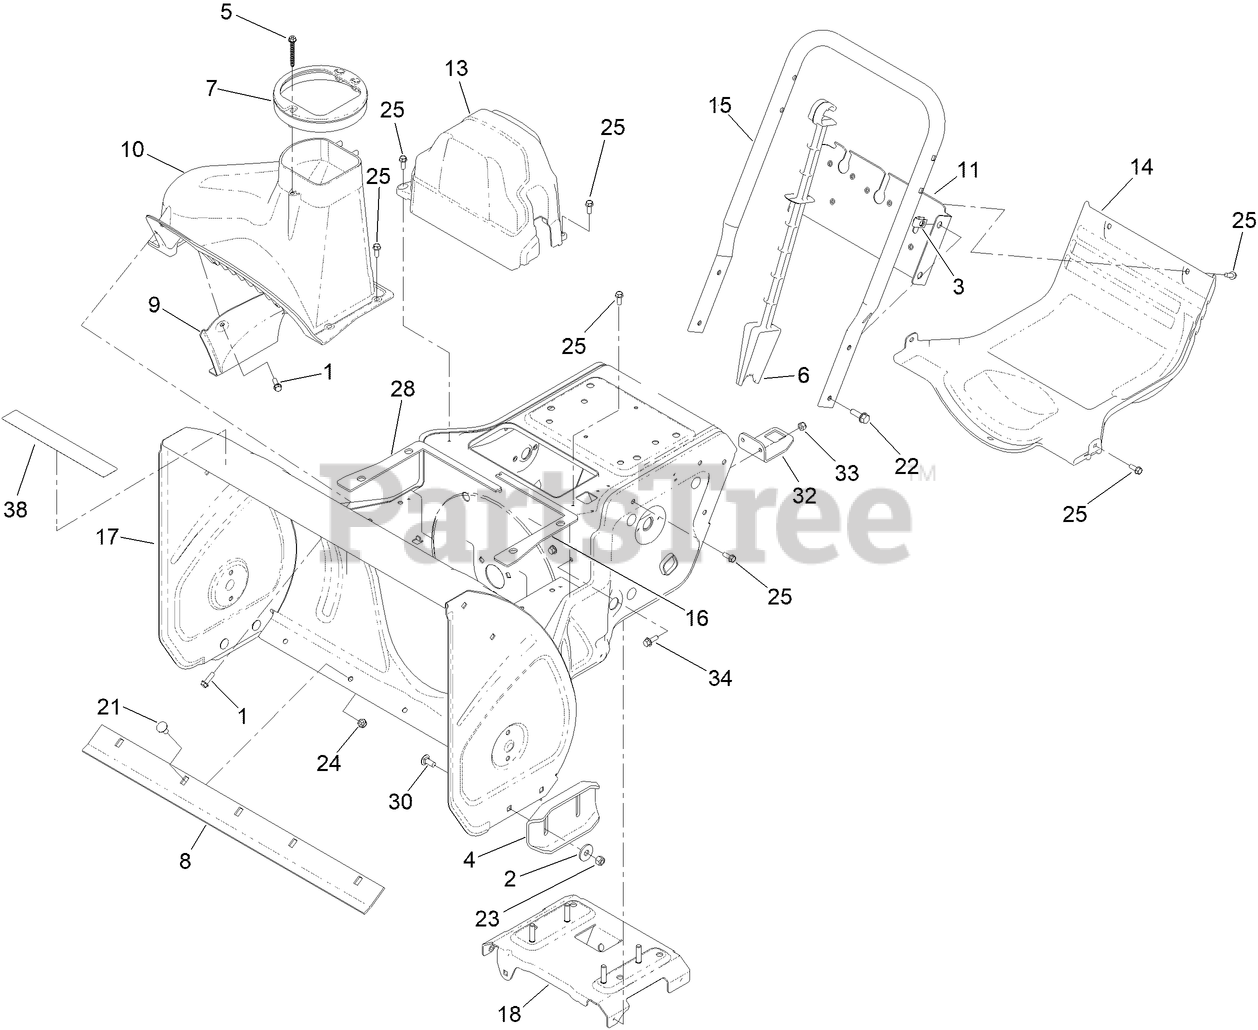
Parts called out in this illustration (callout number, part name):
1	SCREW-PLASTITE, HWH
2	WASHER-FLAT
3	NUT-U
5	SCREW-HWH, PLASTITE
6	STICK-CLEANOUT
7	GUIDE-CHUTE
8	SCRAPER-26 INCH
9	COVER-LINER
11	BRACE-FRAME
13	COVER-BELT
14	COVER-LOWER
15	HANDLE-LOWER, CTS
16	SEAL-HOUSING, LH
17	FRAME ASM
18	BRACE-FRAME
21	BOLT-CARR
22	SCREW-HHF
23	NUT-HEX
24	NUT-HEX
25	SCREW-HWH
28	SEAL-HOUSING, RH
30	BOLT-CARR
32	BRACKET-POST, CHUTE
33	SCREW-HHF
34	NUT-HEX
38	DECAL - HARDENED GEARS
